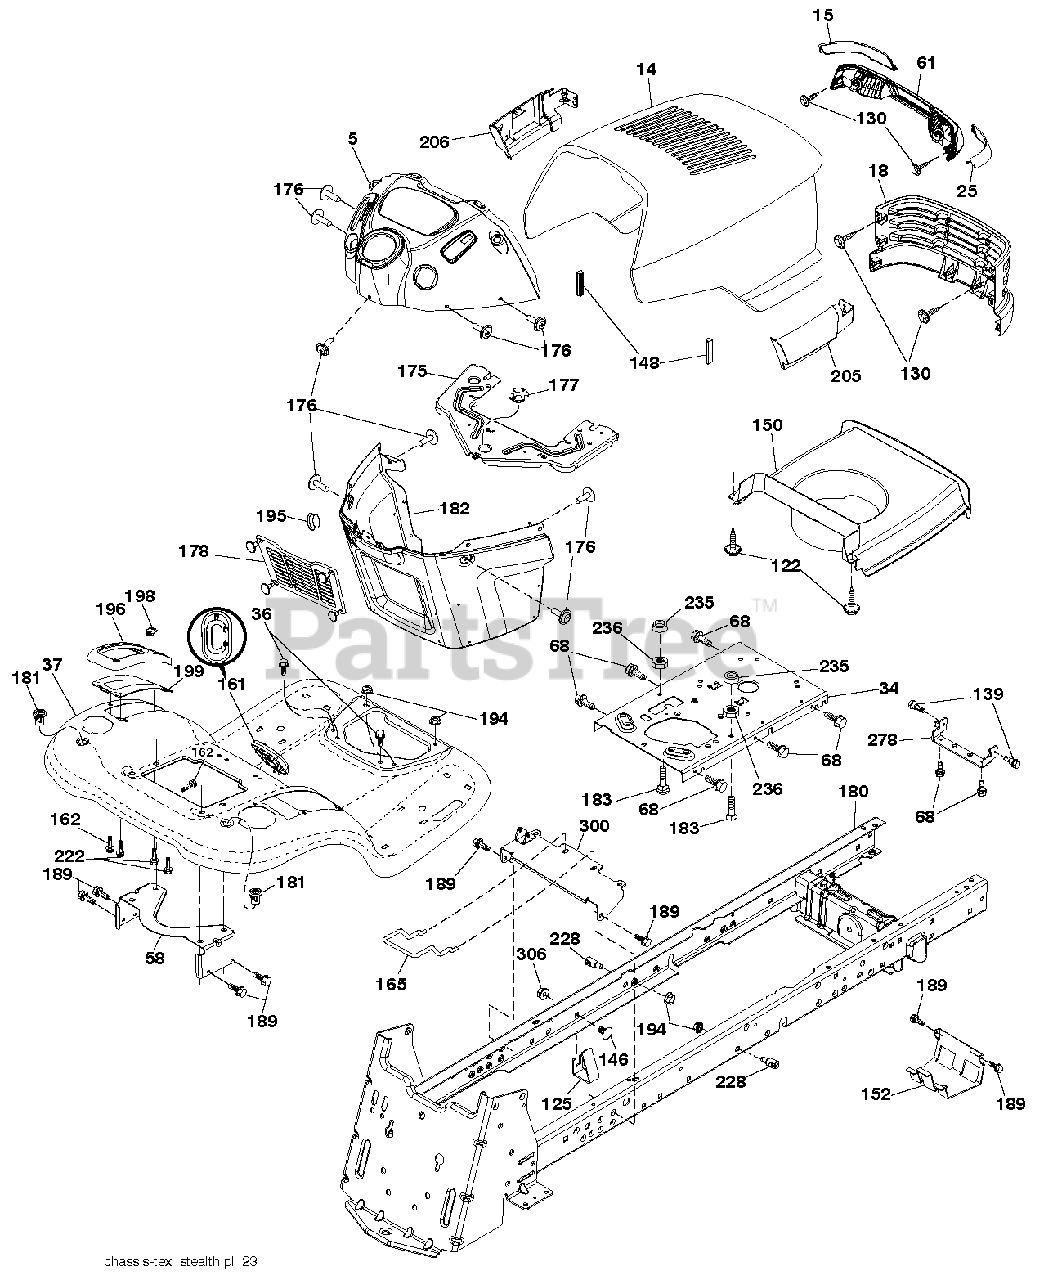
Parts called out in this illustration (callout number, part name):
5	DASH.STEALTH.EL.LIFT.RND.BLACK
14	HOOD.ASM.DIXON.STEATH.SRS.BLUE
15	LENS LH
18	GRILLE.STEALTH.GT.BLACK
25	LENS RH
34	PLATE.ENGINE.WELDED.CHASSIS
36	SCREW 5/16"
37	FENDER.BLUE.TXGT.ERGO.SD.FILL
58	BRKT.SUPPORT.FNDR/TANK
61	LIGHTBOX.ASM.STEALTH.DL.DIXON
68	SCREW LT
122	SCREW.WSHD.HEX10-32X5/8
125	CLIP.FUEL.LINE
130	SCREW.#10 X 0.750.BOS (2 2)
139	BOLT, SHOULDER 5/16-18
146	BOLT.RDHD.SHT.SQNK.3/8-16X5/8
148	EXTRUSION BUMPER
150	DUCT.HEAT.HOOD.STEALTH.GT
152	SHIELD.BROWNING.W/TEX
161	CONSOLE.FUEL.WINDOW.STGT.BLACK
162	SCREW.HI-LO.CONSOLE
165	SUPPORT.TANK.REAR.B/TE
175	CROSSMEMBER.
176	SCREW.#10-24X5/8.RN.QU
177	BUSHING,STEERING
178	CARGO.ASM.NET.DASH.LOWER
180	CHASSIS.GT.SLOPED.DRAWBAR.
181	FEND/FTRST.PCH.CPH.NFW
182	DASH.LOWER.
183	BOLT.5/16-18X1-1/4 FULL THD
189	SCREW
194	NUT LOCK HEX FLANGE 5/16-18
196	CONSOLE.ASM.DECK.
198	INDICATOR.DECK.LIFT.RED
199	PLATE.DECK.LIFT.ELECTRIC
205	SKIRT.GRILLE.STEALTH.RH
206	SKIRT.GRILLE.STEALTH.LH
222	SCREW.1/4-20X5/8
228	STUD.FASTNER.W/ANTI-ROTATE
235	SPACER FENDER
236	NUT.CENTERLOCK.5/16-
278	BRKT.HOOD/MUFF.STEALTH
300	BRACKET.ASM.LIFT.ELECTRIC
306	NUT LOCK FLG 3/8-16 UNC
